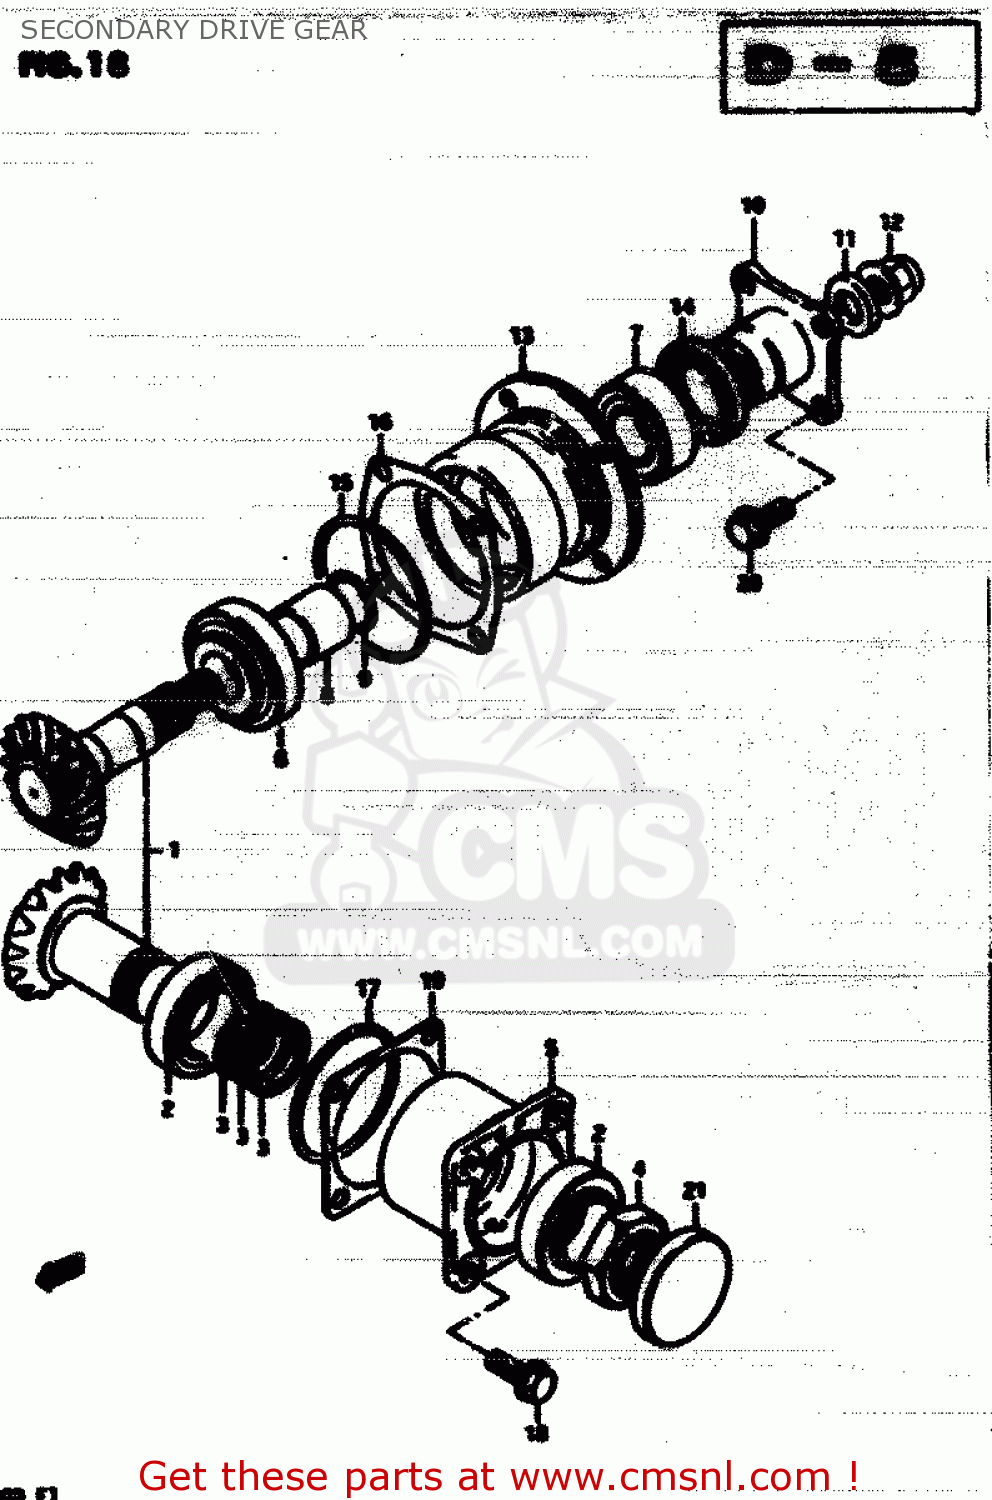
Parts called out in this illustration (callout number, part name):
1	GEAR SET,SECON
2	BEARING(32X58X17)
3	SHIM(32X38X2)
4	NUT
5	HOUSING,SECONDARY DRIVE
6	TAPER,ROLLER BEARING
7	BEARING
8	SPACER (25.2X30X40)
9	SHIM (25X30X2
10	FLANGE,UNIVERSAL JOINT
11	WASHER(14X29X4)
12	NUT
13	HOUSING,SECONDARY DRIVE
14	SEAL,OIL(35X52X9)
15	O RING(D:3.1,ID:69.4)
16	SHIM,DRIVEN GEAR HOUSING
17	O RING(D:2.4,ID:62.6)
18	BOLT
19	SHIM,SECONDARY DRIVE
20	BOLT
21	PLUG
